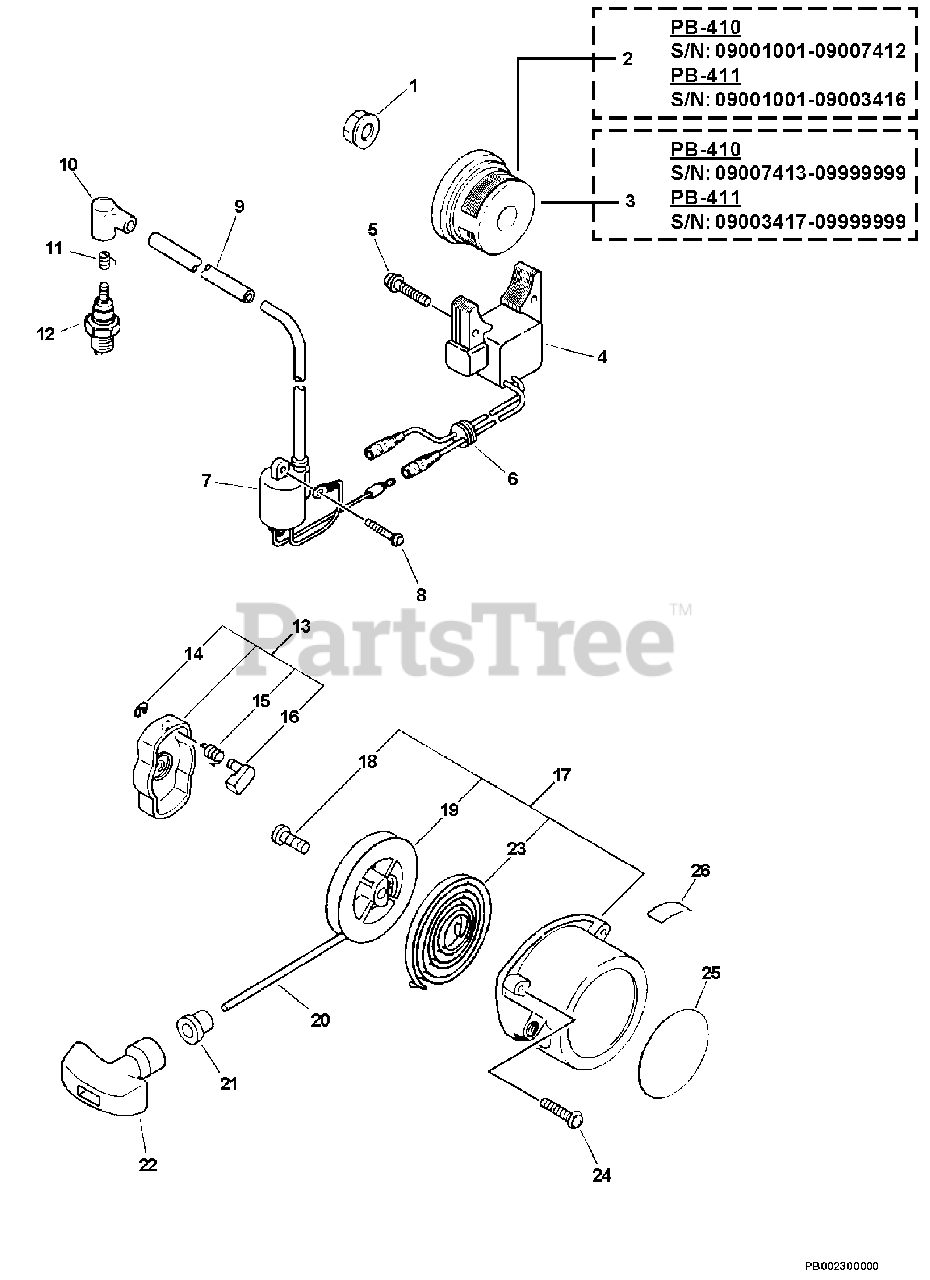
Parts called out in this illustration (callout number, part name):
1	NUT - 10 -- FLANGE
2	FLYWHEEL
3	FLYWHEEL
4	COIL, IGNITION
5	SCREW - 5X25
7	COIL, IGNITION
8	SCREW - 4X16
10	CAP, SPARK PLUG
11	TERMINAL, SPARK PLUG CAP
12	SPARK PLUG -- BPM-8Y
13	STARTER PAWL ASSY
14	RING, RETAINING - 4
15	SPRING, RETURN
16	PAWL, STARTER
17	STARTER ASSY
19	REEL, ROPE
20	ROPE, STARTER - 4X880
21	GUIDE, ROPE
22	GRIP, STARTER
23	SPRING, REWIND
24	SCREW - 5X18
25	LABEL - ECHO
26	LABEL - HOT SURFACE
